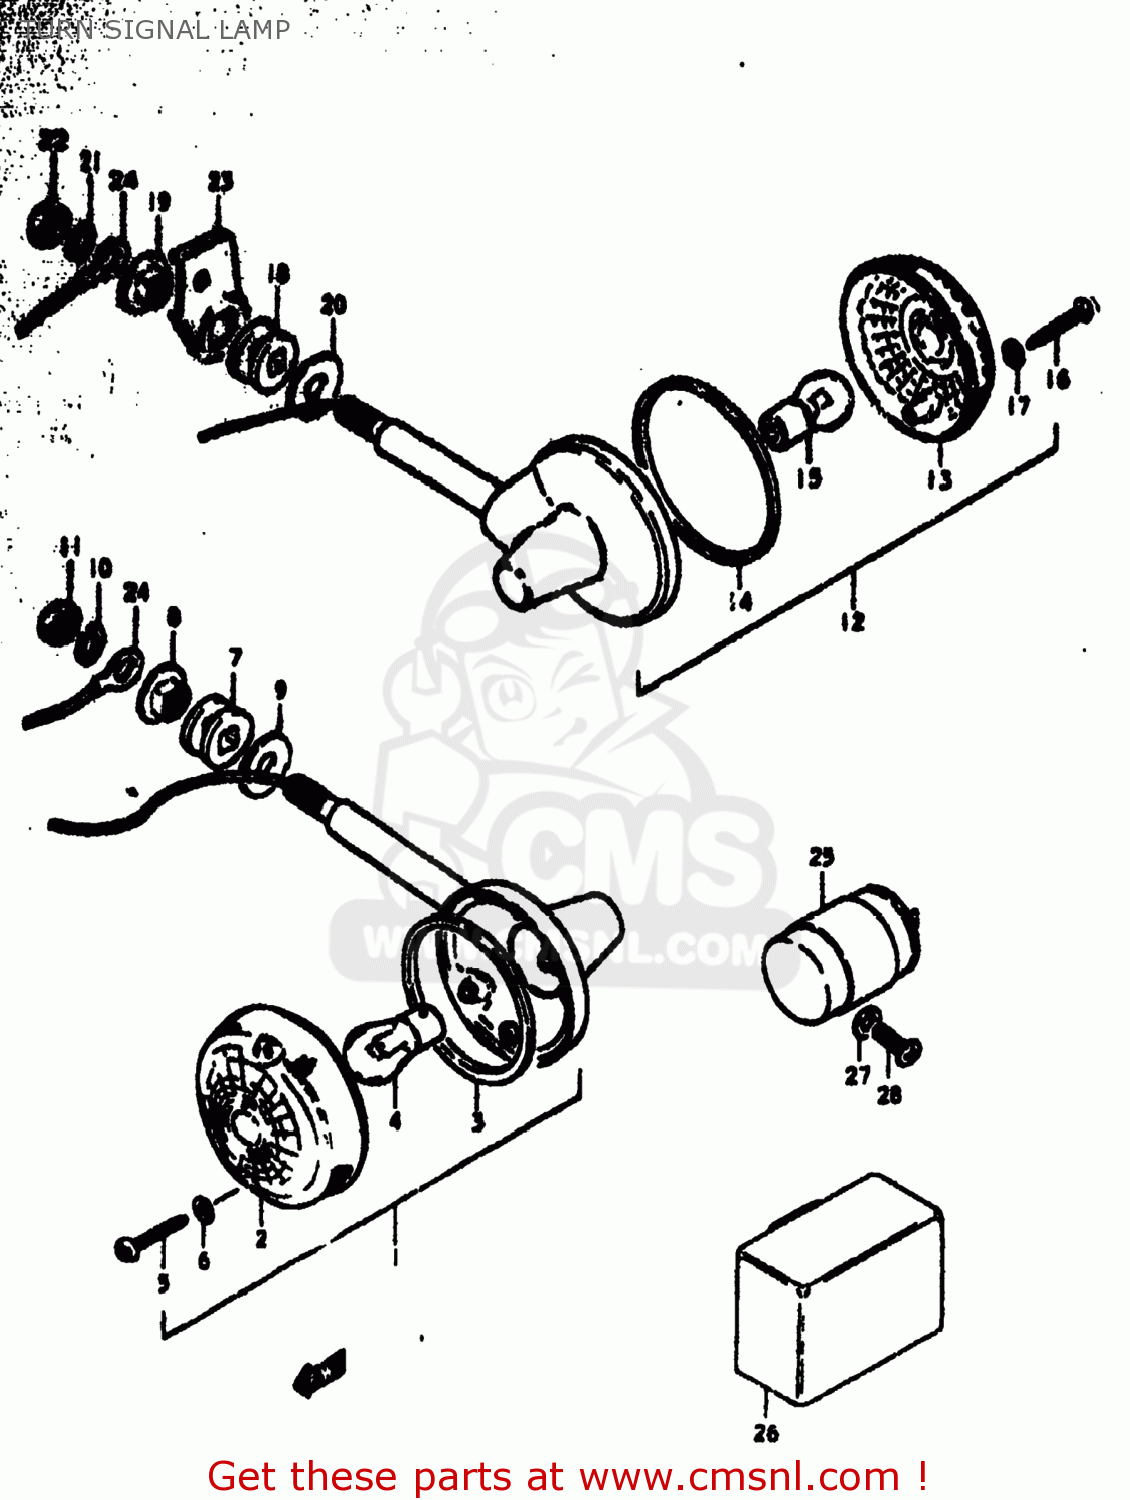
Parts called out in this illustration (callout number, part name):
1	LAMP ASSEMBLY,FRONT TURN SIGNAL
2	LENS
3	GASKET (NAS)
4	BULB(12V23W,STANLEY,A4577A)
5	SCREW
6	GASKET (NAS)
7	CUSHION
8	SPACER,RR TURNSIGNAL LAMP
9	WASHER
10	LOCK WASHER
11	NUT
12	LAMP ASSEMBLY,REAR TURN SIGNAL
13	LENS
14	GASKET (NAS)
15	BULB(12V23W,STANLEY,A4577A)
16	SCREW
17	GASKET (NAS)
18	CUSHION
19	SPACER,RR TURNSIGNAL LAMP
20	WASHER
21	LOCK WASHER
22	NUT
23	BRACKET,RR TURNSIGNAL LAMP,R
24	WIRE
25	RELAY,TURN SIGNAL
26	RELAY,TURN SIGNAL
27	WASHER
28	SCREW
